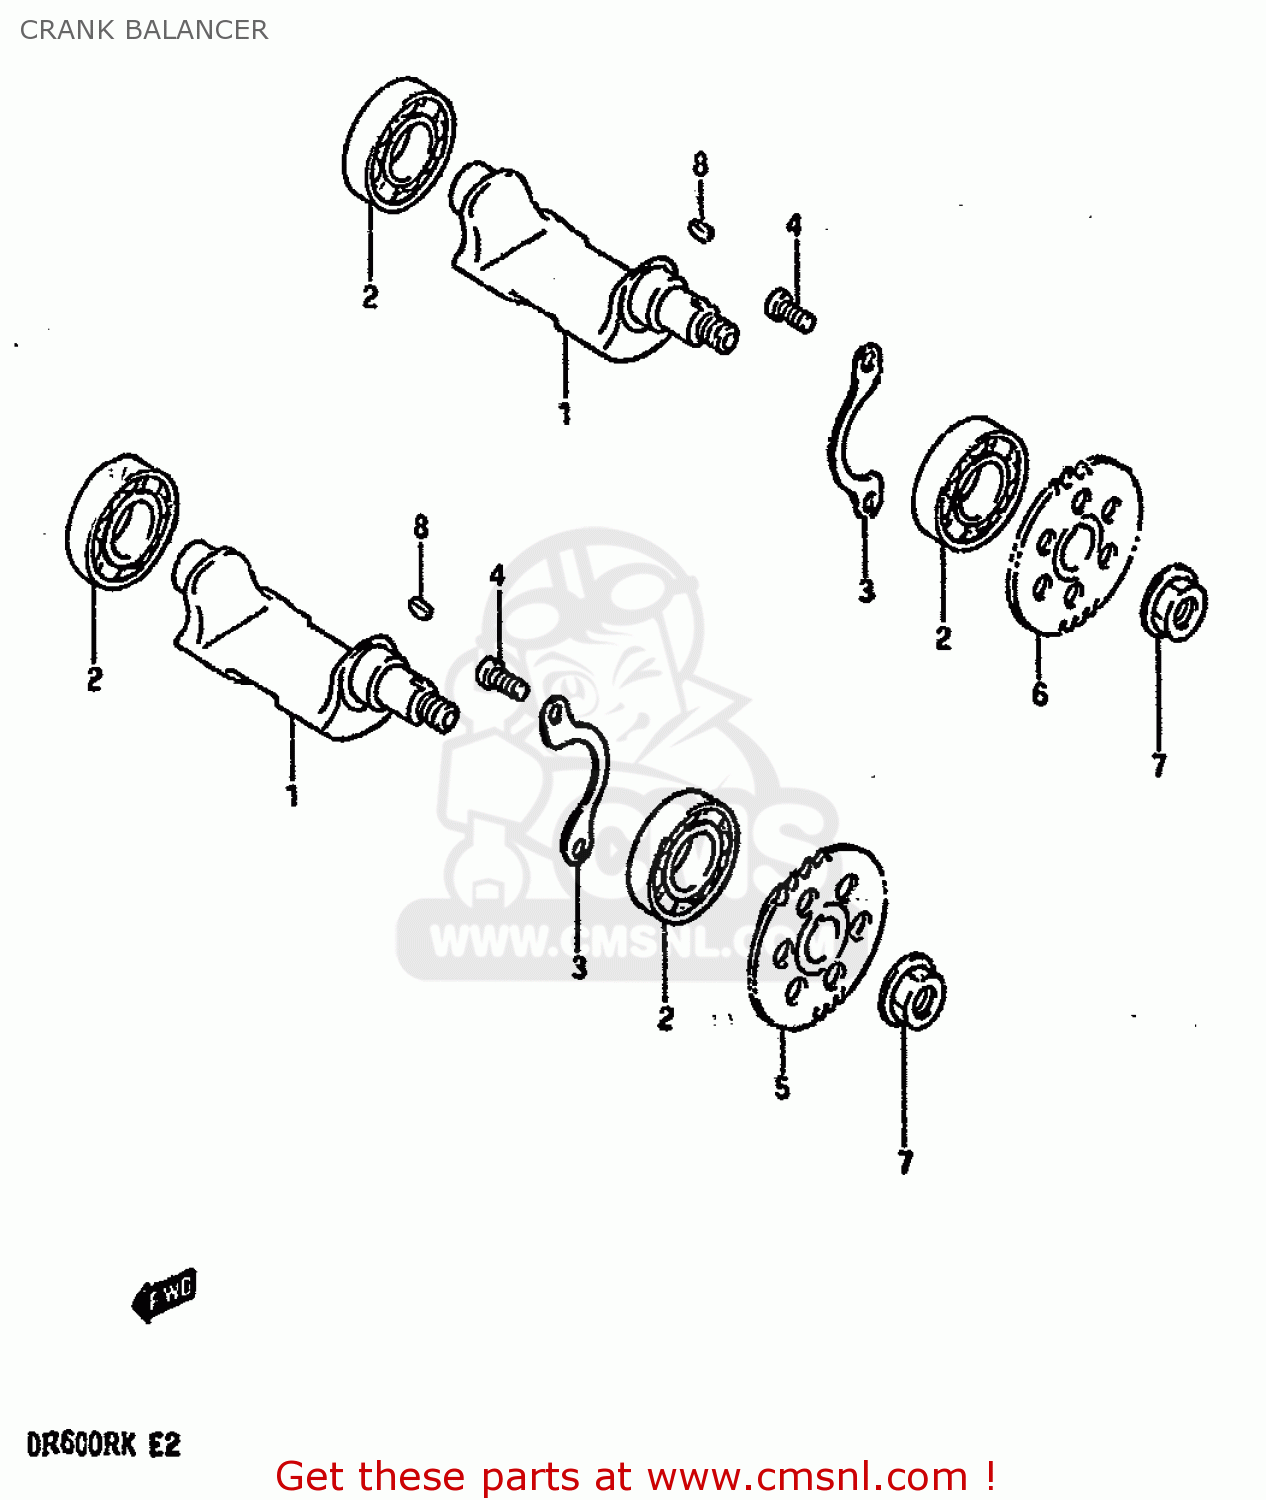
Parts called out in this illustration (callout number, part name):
1	BALANCER,CRANKSHAFT
2	BEARING
3	RETAINER,CRANK BAL BEARING
4	SCREW
5	SPROCKET,BALANCER DRIVE
6	SPROCKET,BALANCER DRIVE
7	NUT
8	KEY
